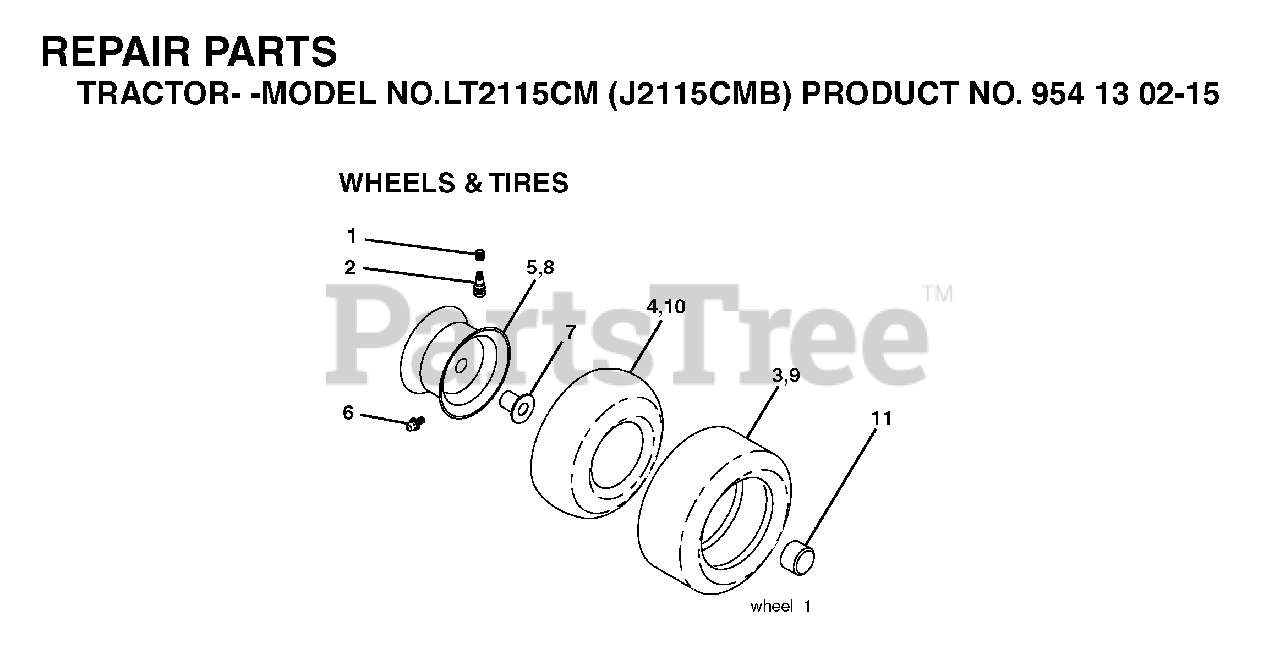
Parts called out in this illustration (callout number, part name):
1	VALVE CAP
2	VALVE STEM LT
3	TIRE HEAVY DUTY
4	TUBE.5.3/4.5/6
5	RIM ASM 6" FRONT SILVER
6	FITTING LT
7	BEARING T
8	RIM ASM 8" REAR SILVER
9	TIRE HEAVY DUTY
10	TUBE
11	CAP, AXLE BLK
